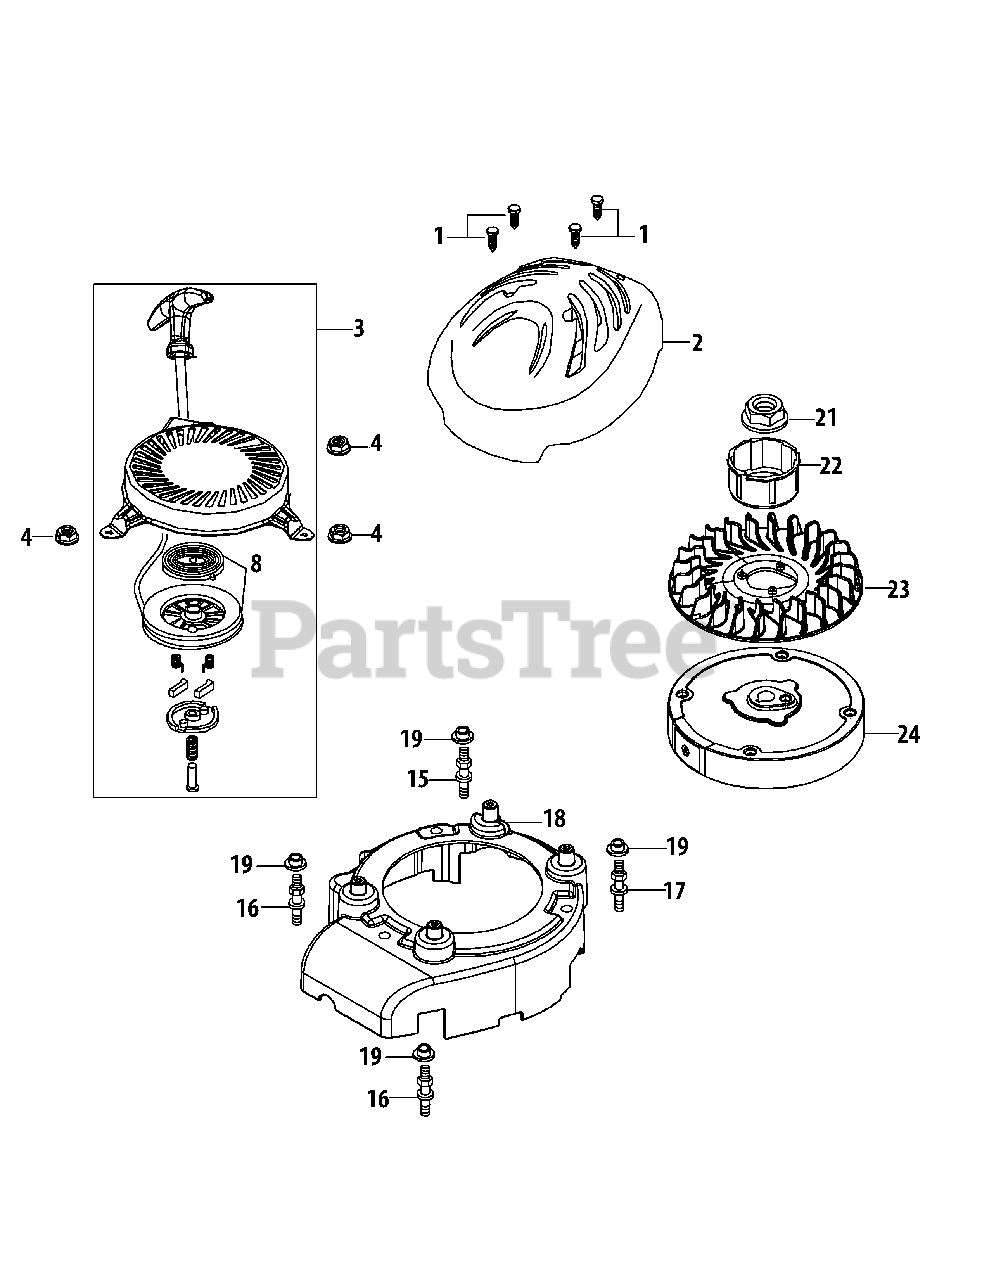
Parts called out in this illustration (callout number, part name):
1	Screw, #12-16 X 1.00"
2	Outer Shroud (Model Specific)
3	Recoil Starter Assembly
4	Nut M6X10Mm
8	Starter Pulley
15	Stud Left/Black/Ye Zinc
16	Stud Front/Unmarked/Ye Zinc
17	Stud Right/White/Ye Zinc
18	Inner Shroud
18	Inner Shroud Assy (Incl.17)
19	Engine Shroud Spacer
21	Flywheel Nut M14
22	Starter Cup
23	Cooling Fan
24	Flywheel
